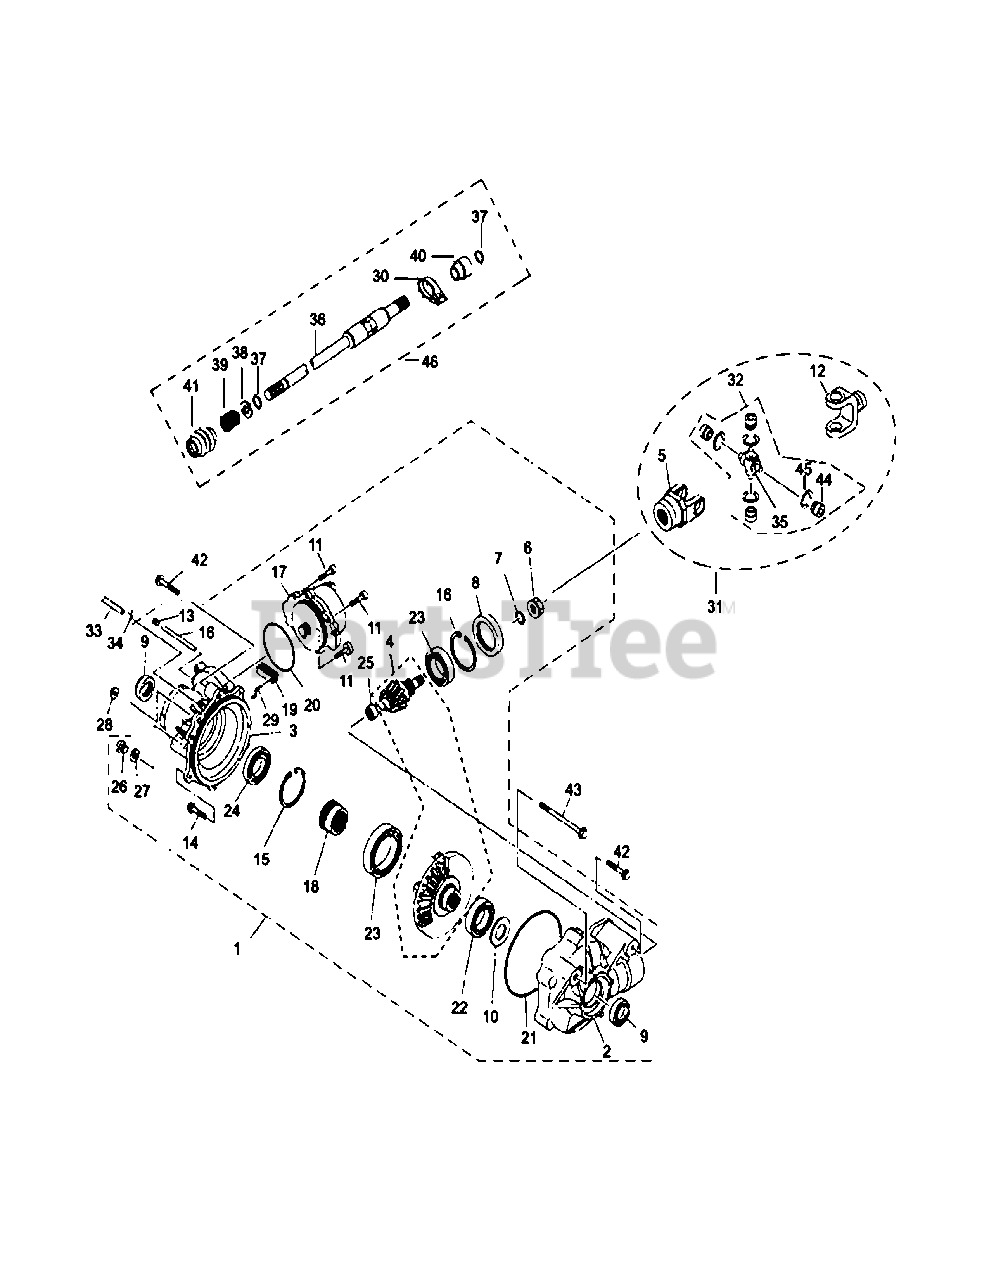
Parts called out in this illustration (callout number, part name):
1	Front Differential Assy
2	Front Differential Case II
3	Front Differential Case I
5	Connection Fork I
7	O-Ring 6.8x14
8	Oil Seal48x65x9
9	Oil Seal24x38x8
10	Washer I 50x61.5
12	Connection Fork II
13	Socket Hexagon Screw M8x10
14	Bolt M10x1.25x16
17	Transfer Case Assembly
18	Divide Device Connection
20	O-Ring2x81,Transfer Case
21	O-Ring 2.62x139.37
22	Bearing 35x62x14
23	Bearing 60x85x13
24	Bearing 35x62x9
25	Bearing 15x21x12
26	Screw
27	O-Ring 13x1.5
28	Hexagon flange nut M10x1.25
29	Shaft Fork IV
30	Clamp20-32
31	Universal Joint I
32	Criss-Cross Shaft (20)
33	Vent Pipe L=700
34	Oil Pipe Clip 8
35	Cross Axle
36	Front Transmission Shaft
37	Circlip D0=19
38	Circlip20x26x1
39	Spring25x2.3x28
40	Front Dust Proof Cover, Front Middle Shaft
41	Rear Dust Proof Cover, Front Middle Shaft
42	Hexagon Flange Bolt M10x1.25x30
43	Hexagon Flange Bolt M10x1.25x142
44	Needle Sleeve
45	Block Ring
46	Front Transmission Shaft Comp
